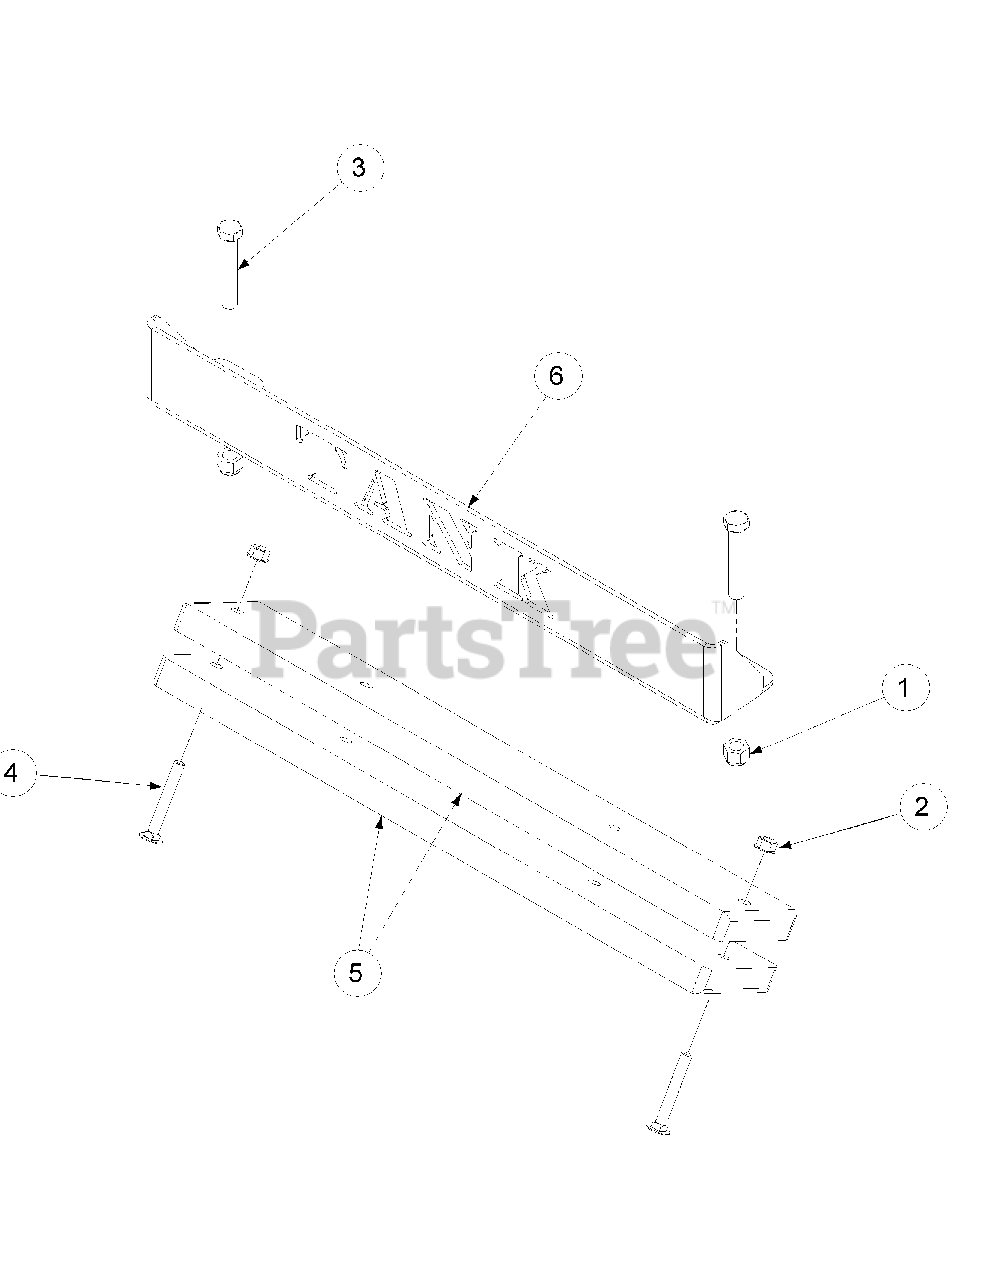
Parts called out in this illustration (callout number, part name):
1	Hex Nut, 1/2-13, Insert Lock
2	Nut, Hex 3/8-16 Flange Lock
3	HHCS, 1/2-13, 3.00
4	Carriage Bolt, 3/8-16, 2.75
5	Bar, Weight
6	Rear Bumper Plate
